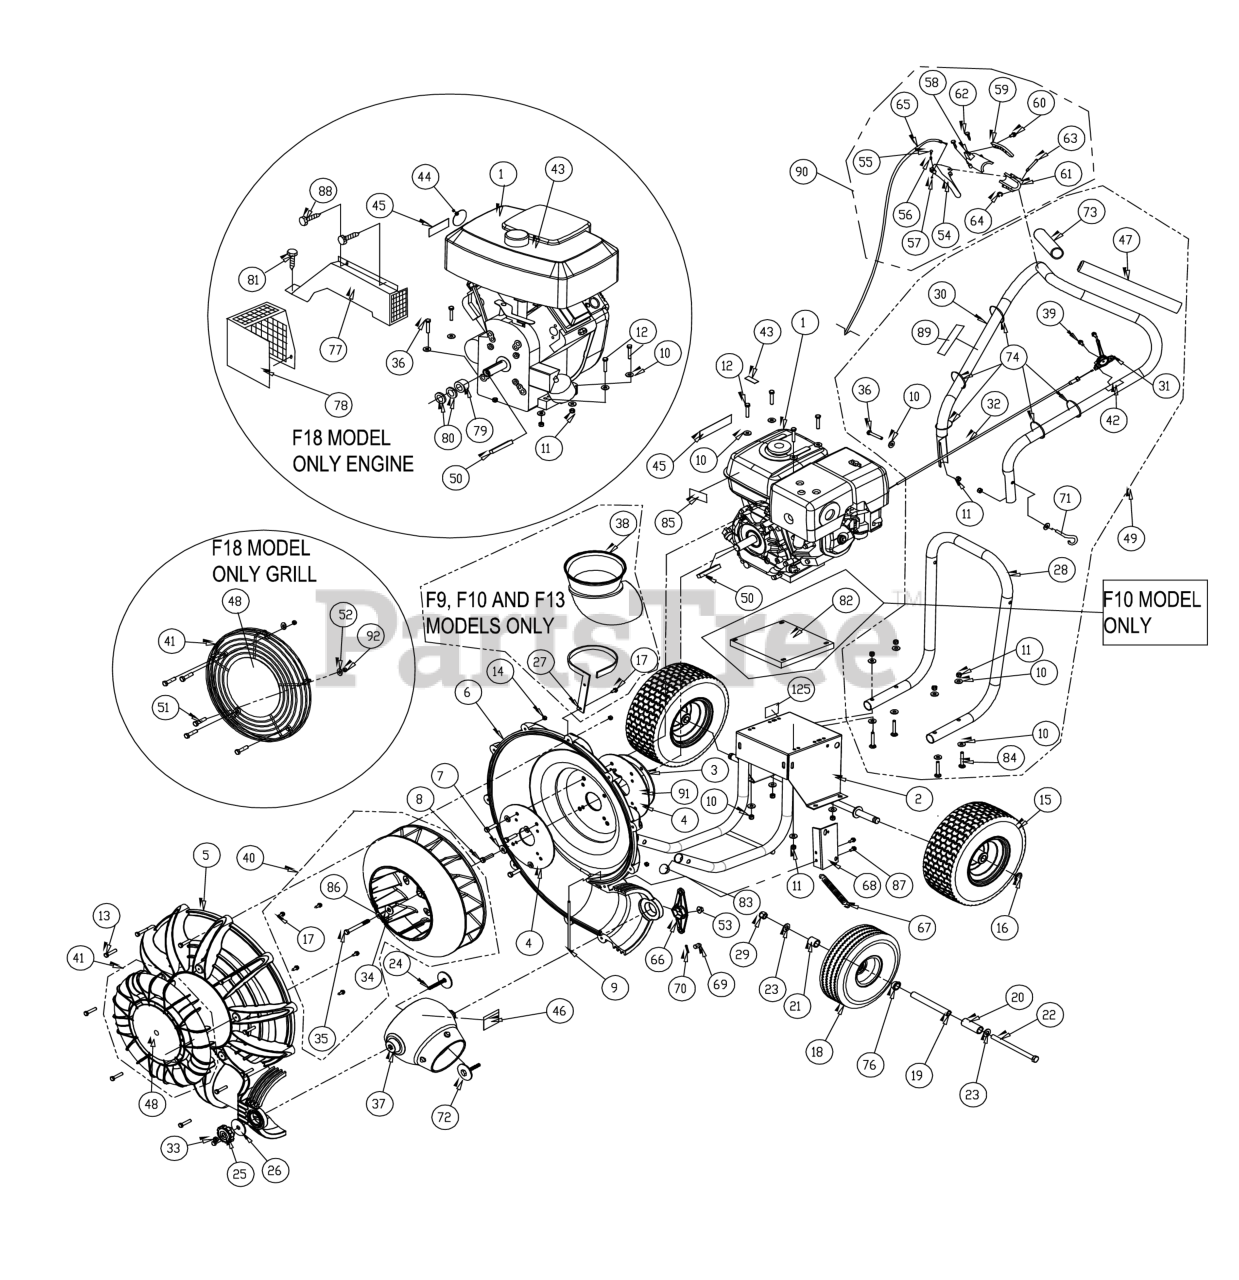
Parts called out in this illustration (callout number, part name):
1	ENGINE HONDA 10PH VANGUARD
2	FORCE PUSH FRAME W/LABELS SERVICE
3	SPACER RING ENGINE
4	PLATE, HOUSING REINFORCEMENT
5	HOUSING FRONT MOLDED
6	HOUSING BACK MOLDED
7	WASHER LOCK 3/8" S/T MED
8	SCREWCAP 3/8" - 16 X 1/2" HCS ZP
9	ROD HAND STOP
10	WASHER 5/16" FLATWASHER Z/P
11	NUT LOCK 5/16"-18 HEX Z/P
12	SCREWCAP 5/16"-18X2 1/2" HCS ZP
13	SCREWCAP 1/4"-20X1 1/2" HCS ZP
14	NUT WHIZ 1/4"-20 WASH FACE
15	WHEEL & TIRE 13" X 5" PNEUMATIC
16	RING RETAINING "E" 3/4"
17	SCREW SM 1/4"X3/4" TYPE A HX WF
18	WHEEL ASSY PNEUMATIC
19	SPACER AXLE FRONT
20	SPACER LH WHEEL FRONT
21	SPACER RH WHEEL FRONT
22	SCREWCAP 1/2"-13 X 9 1/2" HCS ZP
23	WASHER 1/2" SAE Z/P
24	WASHER W/BOLT WA
25	KNOB 3/8-18, SOLID HUB
26	WASHER 2.25 OD X .515 ID X .134 ZP
27	BRACKET EXHAUST FRONT
28	HANDLE LOWER
29	NUT LOCK 1/2"-13 HEX
30	HANDLE UPPER
31	CONTROL THROTTLE BLOWER
32	CABLE THROTTLE BLOWER
33	NUT LOCK 3/8-16 LT WT THIN ZP
34	WASHER 1.5 OD X 0.453 ID X 0.5
35	SCREWCAP 7/16"- 20 X 2 3/4" GR. 8 W/PATCH
36	SCREWCAP 5/16"-18X2" HCS ZP
37	DIRECTOR CONE 4" W/LABEL
38	DIVERTER FRONT 4" (NEW STYLE)
39	SCREW SELFTAP #10-24 X 3/8"ZP
40	IMPELLER SERVICE KIT FORCE
41	GRILL KIT GEN II
42	LABEL THROTTLE CONTROL
43	LABEL HOT ENGINE
45	LABEL SAFETY PROTECT READ MANUAL
46	LABEL DANGER FLYING DEBRIS
47	SEE: 440146
48	LABEL FORCE GEN II
49	SEE: 440104-S
50	KEY 1/4" SQ X 3 1/4"
53	NUT LOCK 1/4- 20 2 WAY
54	LEVER DIVERTER
55	PIN LATCH DIVERTER
56	SPRING COMPRESSION 0.281 X 0.88
57	RING RETAINING 3/16" E-CLIP
58	SADDLE LOWER DIVERTER
59	PLATE LOCK DIVERTER
60	SCREW PLASTITE #6-19 X 5/8" HWH ZP
61	SADDLE UPPER DIVERTER
62	SCREW PLASTITE #10-14 X 1" HWH ZP
63	PIN PIVOT DIVERTER CONTROL
64	RING RETAINING 5/16"
65	CABLE DIVERTER
66	DIVERTER REMOTE ADAPTER
67	SPRING EXTENSION .468 X 5.25
68	BRACKET DIVERTER FORCE
69	PIN CLEVIS 1/4" X .75"
70	PIN CLIP HITCH 0.051 X 3/4"
71	EYEBOLT, PIGTAIL 5/16"-18 X 1 1/4"
72	ADAPTOR MOUNT WA
73	GRIP 1-1/4" ID X 9.5" LONG
76	FORCE WHEEL BEARING .751 ID
82	SPACER PLATE WELDMENT
83	PLUG TUBE INSERT 1.25" O.D.
84	BOLT CARRIAGE 3/8"-16 X 2" ZP
85	SEE: 100256
86	WASHER LOCK 7/16" S/T MED
87	SCREW PLASTITE 1/4-10 X 3/4 HWH ZP
89	FORCE AIM AND SHOOT LABEL
90	DIVERTER ASSY
